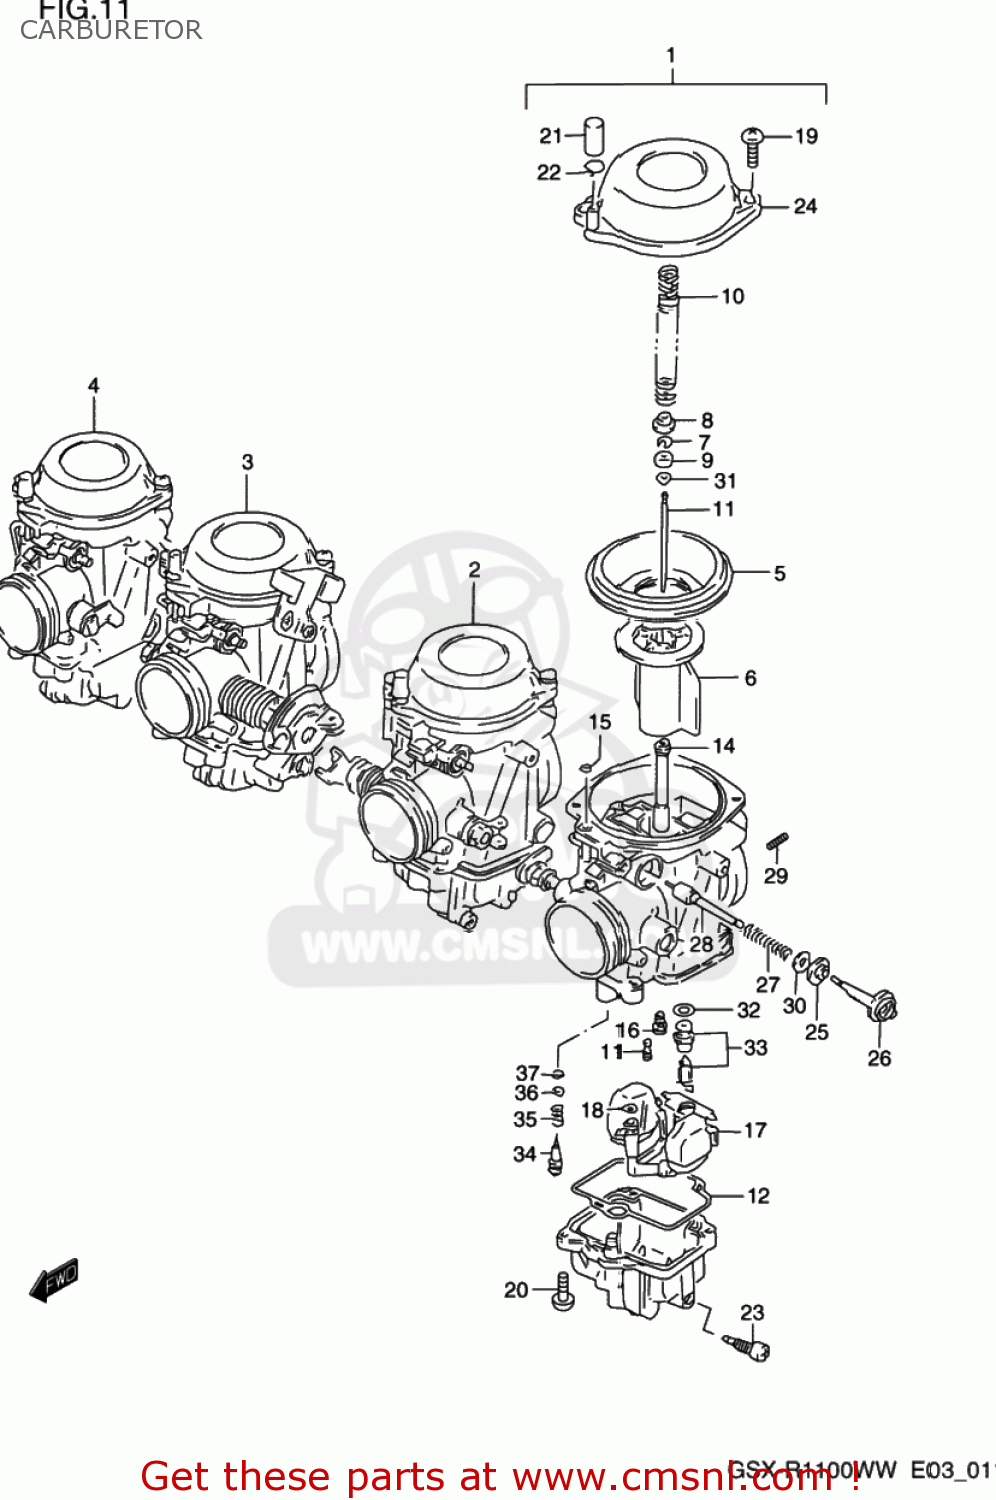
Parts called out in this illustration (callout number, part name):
1	CARBURETOR ASSEMBLY,LEFT
2	CARBURETOR ASSEMBLY,MIDDLE,LEFT
3	CARBURETOR ASSEMBLY,MIDDLE,RIGHT
4	CARBURETOR ASSEMBLY,RIGHT
5	DIAPHRAGM
6	VALVE,PISTON
7	CLIP
8	RING
9	RING
10	SPRING
11	NEEDLE,JET
12	GASKET,FLOAT CHAMBER (NAS)
13	JET,PILOT(30)
14	JET,NEEDLE (O-8)
15	O RING
16	JET,MAIN(117.5)
17	FLOAT/NEEDLE VALVE ASSY
18	O RING
19	SCREW
20	SCREW
21	CAP
22	CLIP
23	SCREW,DRAIN
24	COVER,DIAPHRAGM
25	CAP,STARTER
26	HOLDER,GUIDE
27	SPRING
28	PLUNGER ASSY
29	JET,AIR(1.2)
30	WASHER
31	WASHER
32	O-RING,NEEDLE VALVE
33	VALVE ASSEMBLY,NEEDLE
34	SCREW,PILOT
35	SPRING
36	WASHER
37	O RING,PILOT AIR SCREW
